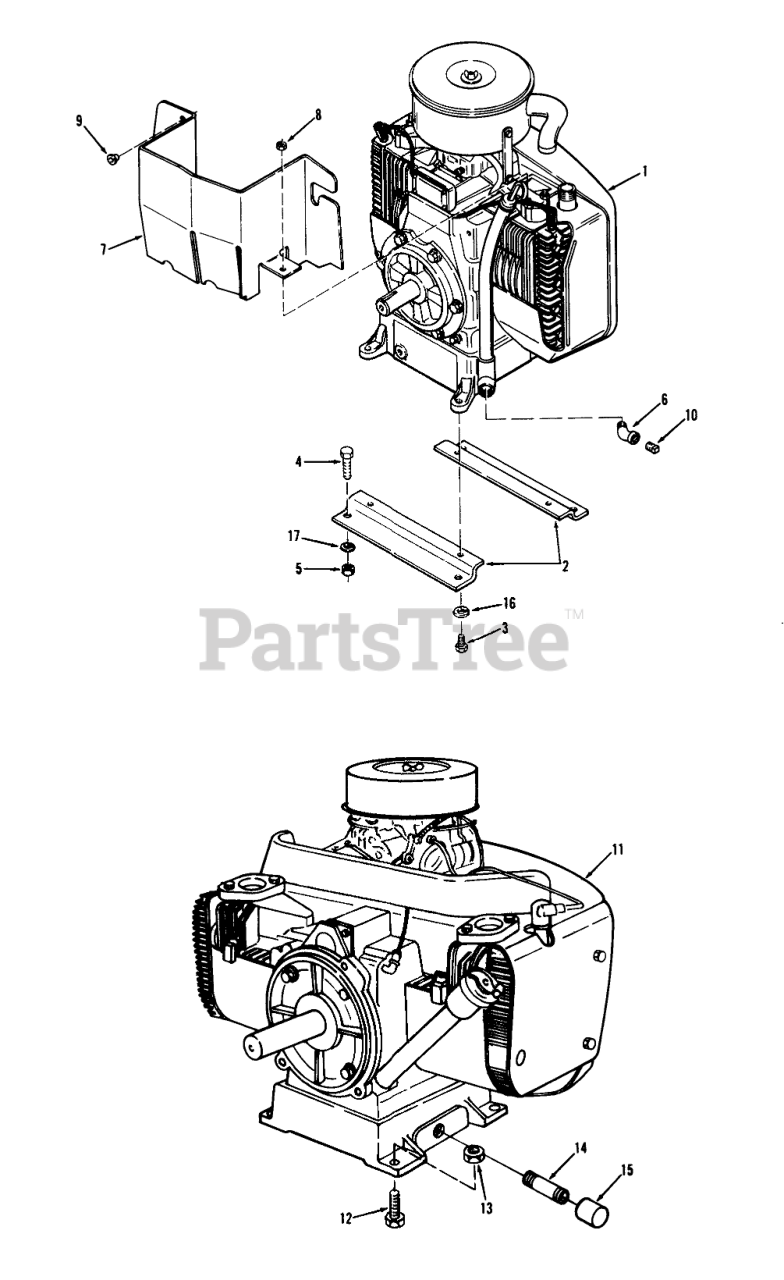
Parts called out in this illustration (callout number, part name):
1	Engine-16 HP Onan
2	Bracket-Engine
3	Bolt
4	Bolt
5	Eslok Nut
6	Street Elbow 1/2 X 45
7	Heat Shield
8	Nut
9	BUSHING-NYLON .75
10	ELBOW
11	Engine 19.9 HP Kohler
12	Hhcs
13	Nut
14	Nipple 3/4 Pipe X2
15	Cap-3/4 Pipe
16	LOCKWASHER
17	WASHER 5/16 SAE
